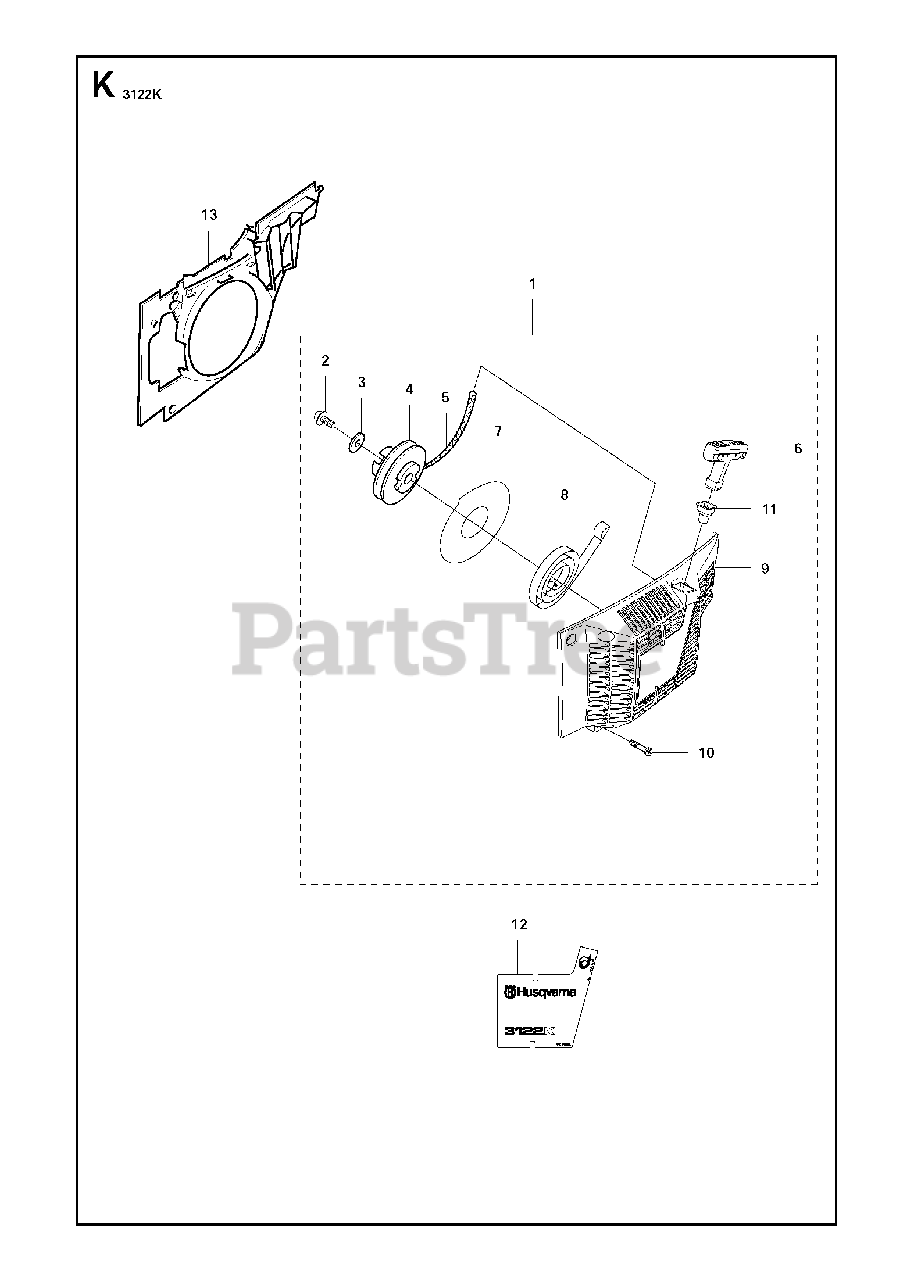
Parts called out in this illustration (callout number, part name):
1	STARTER ASSYIncl. 2 - 10
2	SCREW IHSCT
4	STARTER PULLEY
5	STARTER CORD
5	STARTER CORD50m
6	STARTER HANDLE
7	DAMPING DISC
8	RECOIL SPRING
9	STARTER HOUSING
10	SCREW ITXSCM
13	AIR CONDUCTOR
